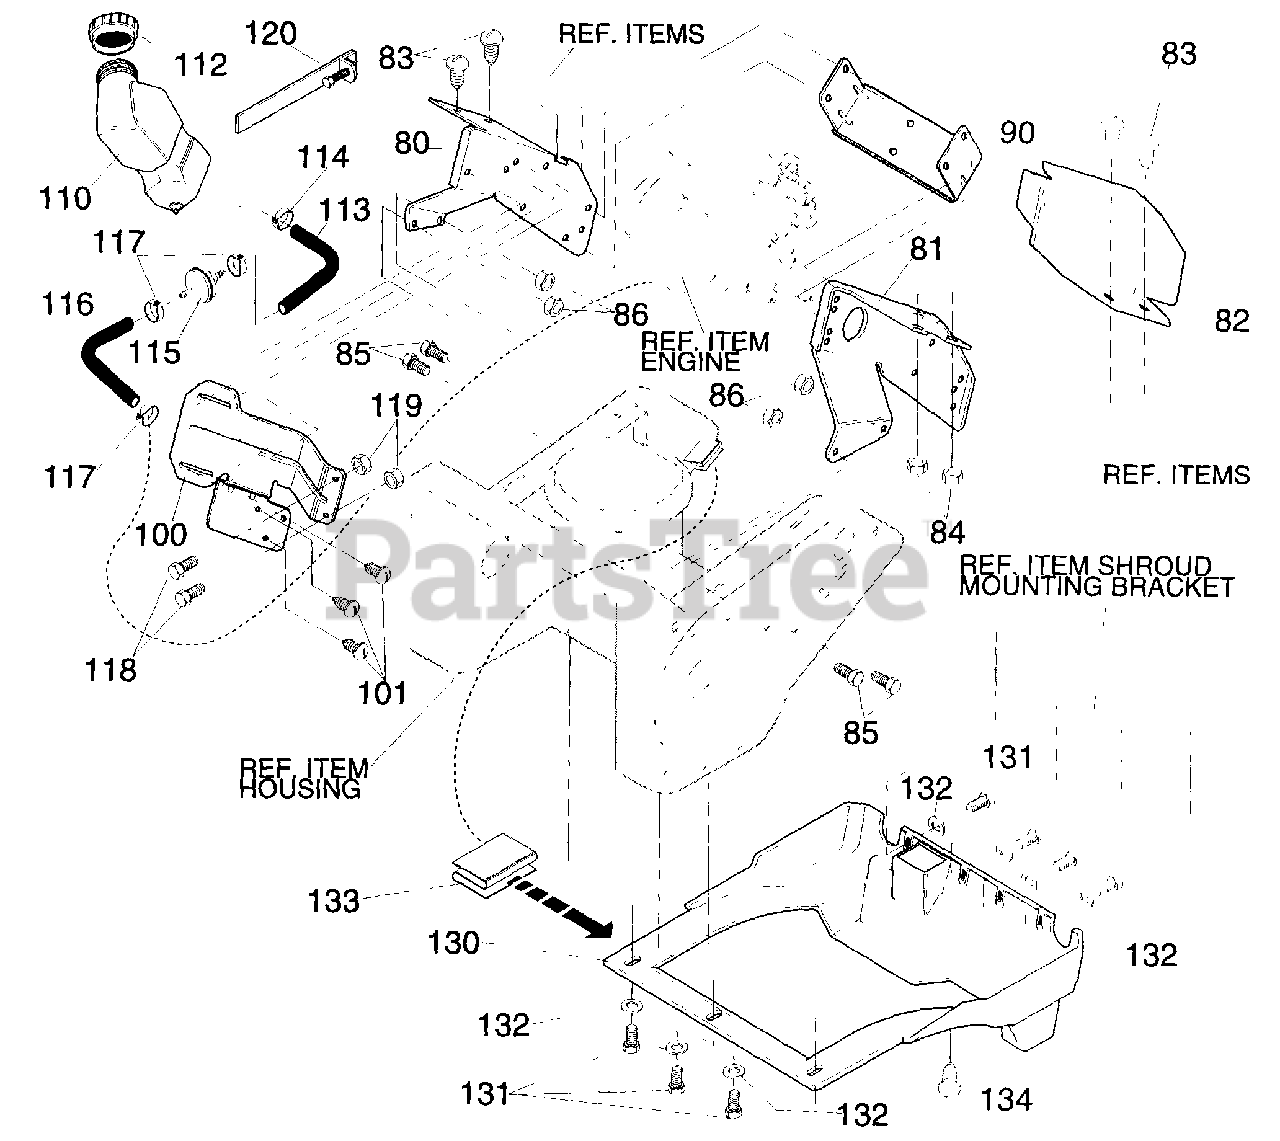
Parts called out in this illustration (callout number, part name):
80	PLATE, REAR MT. RH
81	PLATE, REAR MT. LH
82	SHIELD, ENGINE HEAT
83	SCREW, 1/4-20 X .63
84	NUT, 1/4-20 WDFL
85	SCREW, 5/16-18 X .50 HHC
86	NUT, 5/16-18 REGHEXCTRLK
90	SUPPORT, FRAME ENG. MNT
100	BRACKET, GAS TANK 2CY
101	SCREW, #10-24 X .63
110	TANK, FUEL, 1.62 QT.
112	CAP,FUEL,W/2654 SEAL
113	TUBING, GAS LINE 8 IN.
114	CLAMP,HOSE SCREW TYPE
115	FILTER, IN-LINE
116	TUBING, GAS LINE 3 IN.
117	CLAMP, HOSE
118	SCREW, 10-24 X .50
119	NUT, #10-24 REGHEXCTRLK
120	CLAMP, WORM DR
130	SHROUD, BOTTOM
131	SCREW, #10-24 X .63
132	FLATWASHER .203 X .56 X .040
133	CLIP, "S" TINNERMAN
134	SCREW, 10-16 X .50
